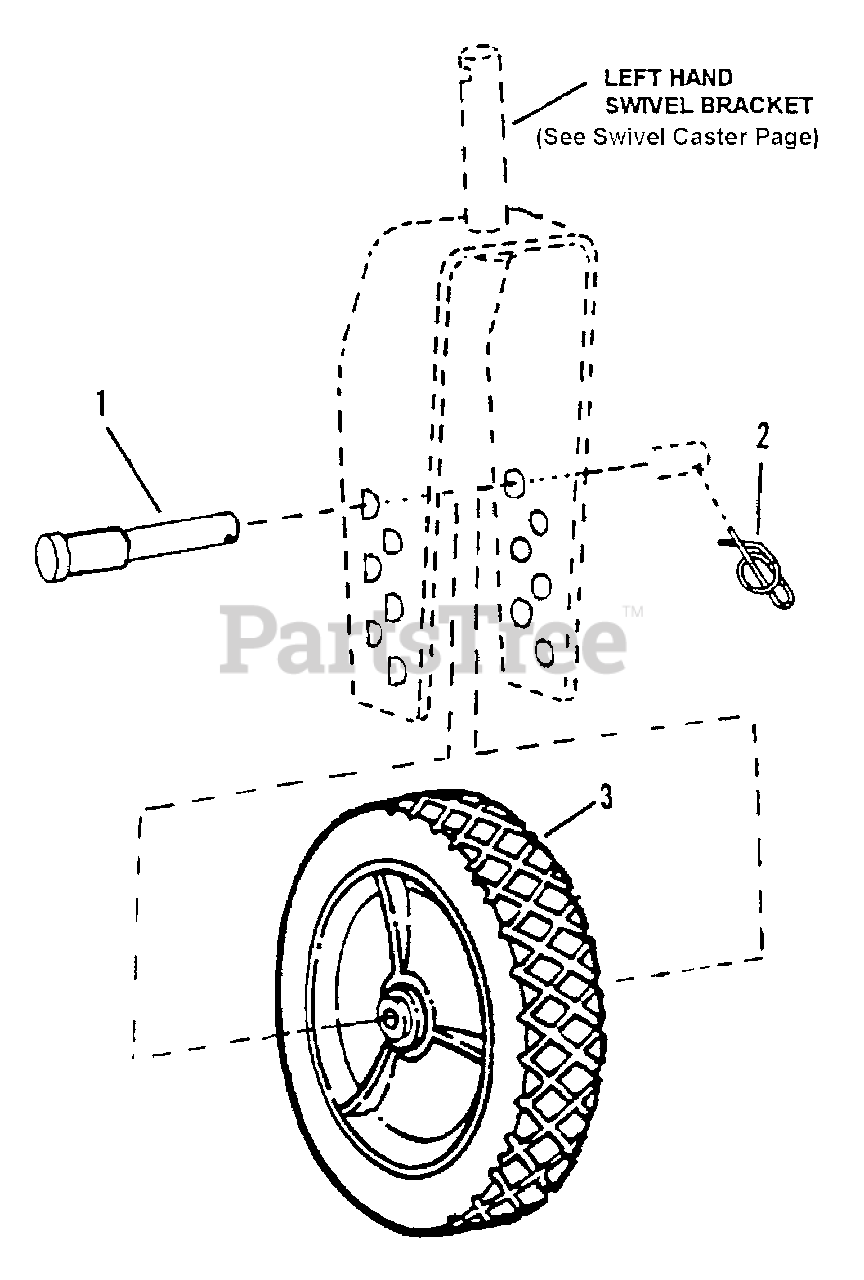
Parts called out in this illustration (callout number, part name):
1	PIN, Wheel - Stepped .435 DIA x 2.725 Long
2	PIN, Swivel Wheel Lock
3	WHEEL, 8 x 1.75 Plastic - Gray
